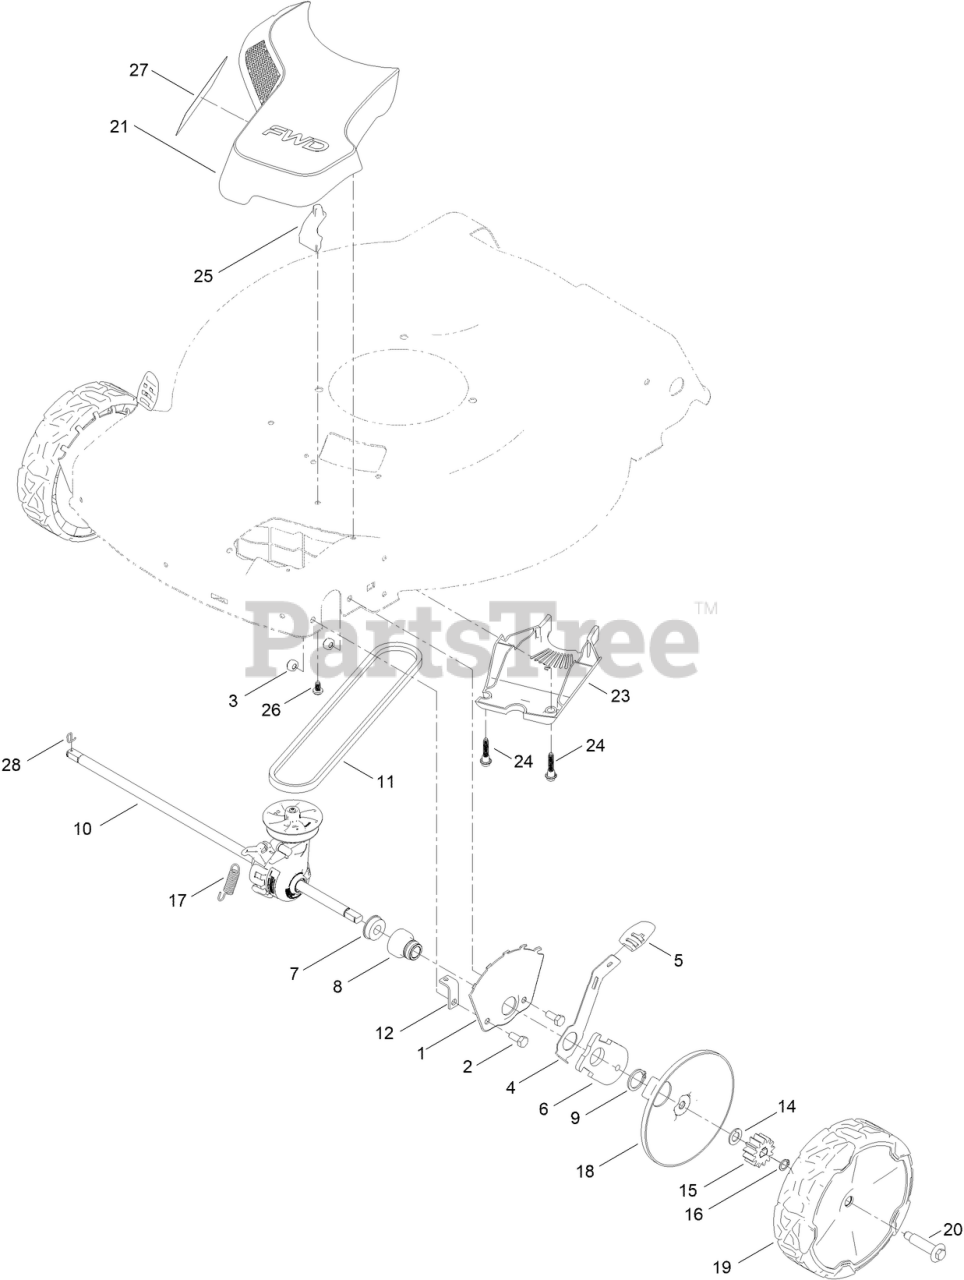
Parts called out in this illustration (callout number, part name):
1	PLATE-HOC,FRONT FSVQ WEDNESDAY
2	SCREW-HH
3	NUT-HEX
4	ARM-SPRING
5	KNOB-LEVER, HOC
6	ARM-PIVOT, FRONT
7	BEARING-BALL
8	RETAINER-BEARING, HOC
9	RING-RETAINING
10	TRANSMISSION-FWD
11	V-BELT
12	TAB-MOUNT, CABLE
14	WASHER-THRUST
15	GEAR-PINION, 13T
16	RING-RETAINING
17	SPRING-EXTENSION
18	ASM-COVER, WHEEL (DK GRAY)
19	ASM-8" WHEEL, FWD (BUSHINGS)
20	WHEEL BOLT
21	ASM-INTAKE, FWD
23	COVER-BELT, LOWER (AWD)
24	SCREW-SHOULDER, HHF
25	PAD-STOP
26	SCREW-PLASTIC,PH
27	DECAL-VORTEX AWD
28	PIN-SNAP
